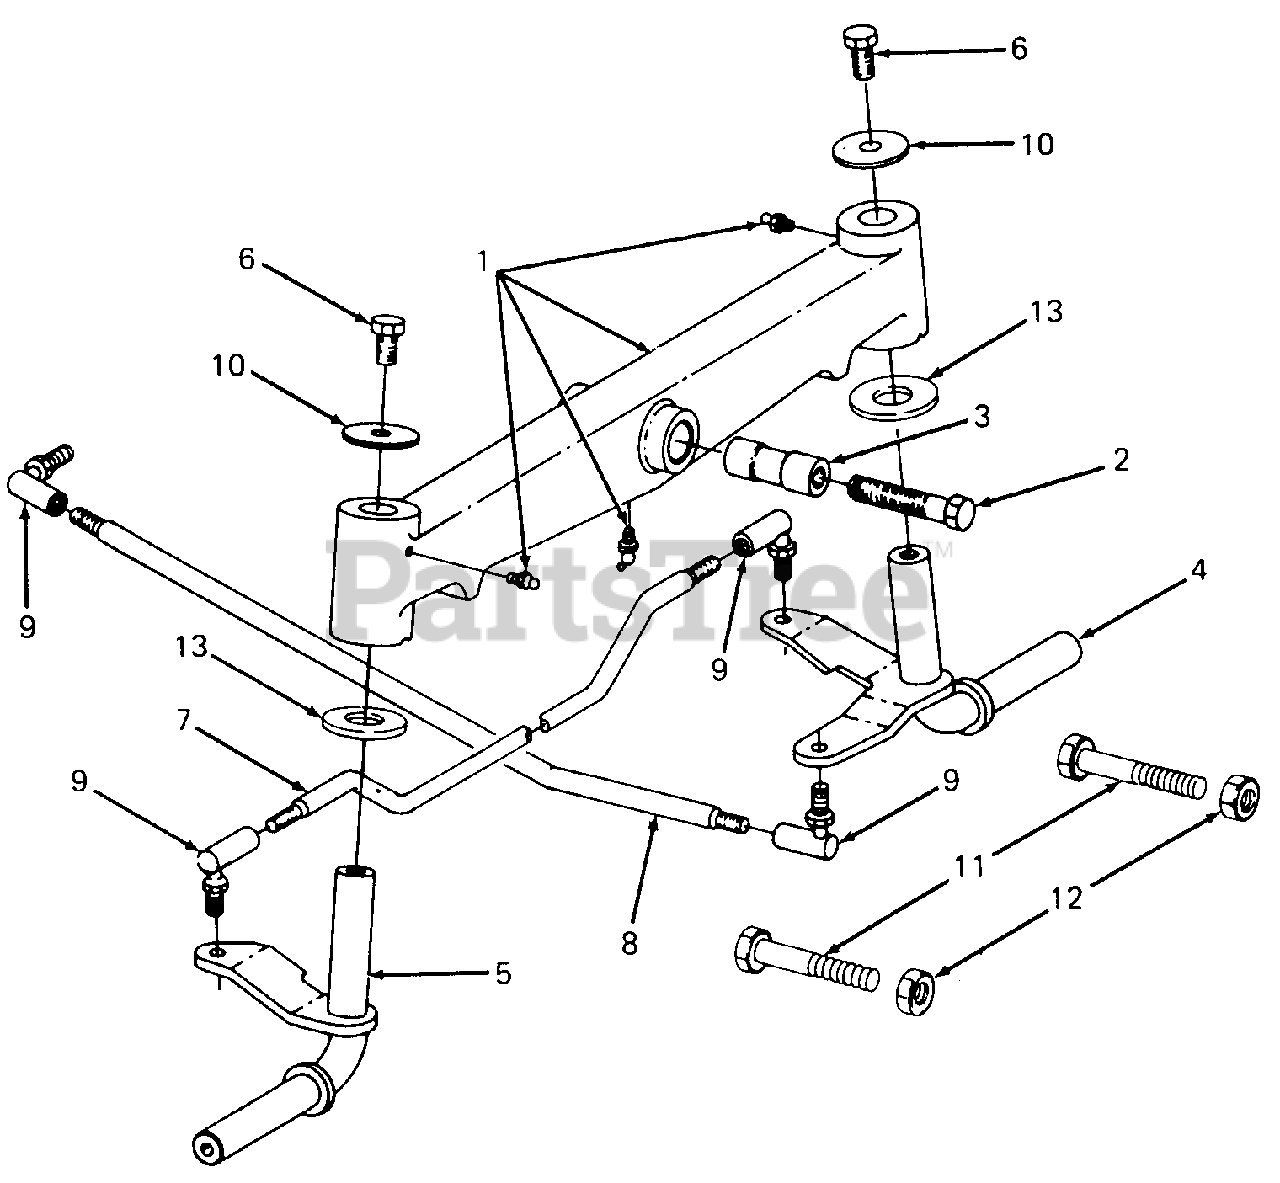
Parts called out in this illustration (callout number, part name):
1	Axle, Front
2	Bolt, 1/2-20 X 4.0 Lg GR5
3	Bushing, Axle Pivot
6	Bolt, 3/8-16 X 3/4 Lg GR5
7	Link, Drag
8	Link, Drag
9	Joint, Ball, 3/8-24 Type G
10	Washer, .406 X 1.50 X 11 ga.
11	Bolt, 3/8-16 X 1.25 GR5
12	Nut, 3/8-16 GR5
13	Washer, .79 X 1.49 X .06 HDN
